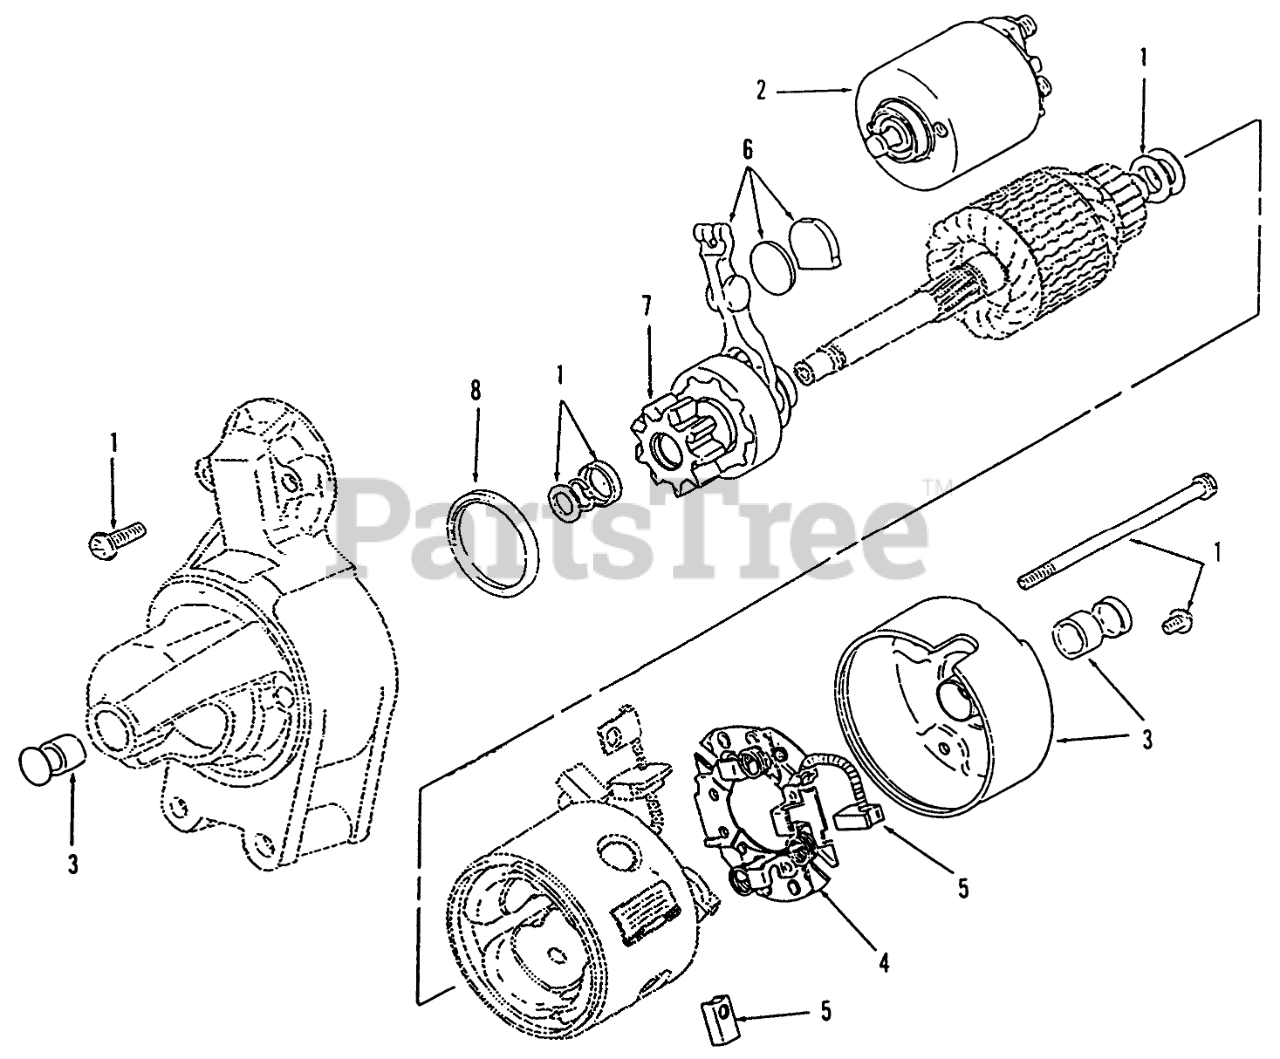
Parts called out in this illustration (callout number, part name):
1	Kit, Hardware-Starter (Includes (2) Solenoid Mtg Screws, 2 Thru Bolts, Armature Shims, Pinion Collar and Retaining Ring)
2	Kit, Solenoid-Starter (Includes Solenoid and Spring Plunger)
3	Kit, Bushing-Starter (Includes Rear Cap with Bushing and Front Bushing)
4	Holder, Brush (Includes Negative Brush)
5	Kit, Brush-Starter (Includes (2) Negative and (1) Positive Brushes)
6	Kit, Shift Lever-Starter (Includes Lever, Wear Plate and Rubber Plug)
7	Clutch Assembly, Starter (Includes Pinion Gear)
8	Dust Seal
9	SPRING-BRUSH
